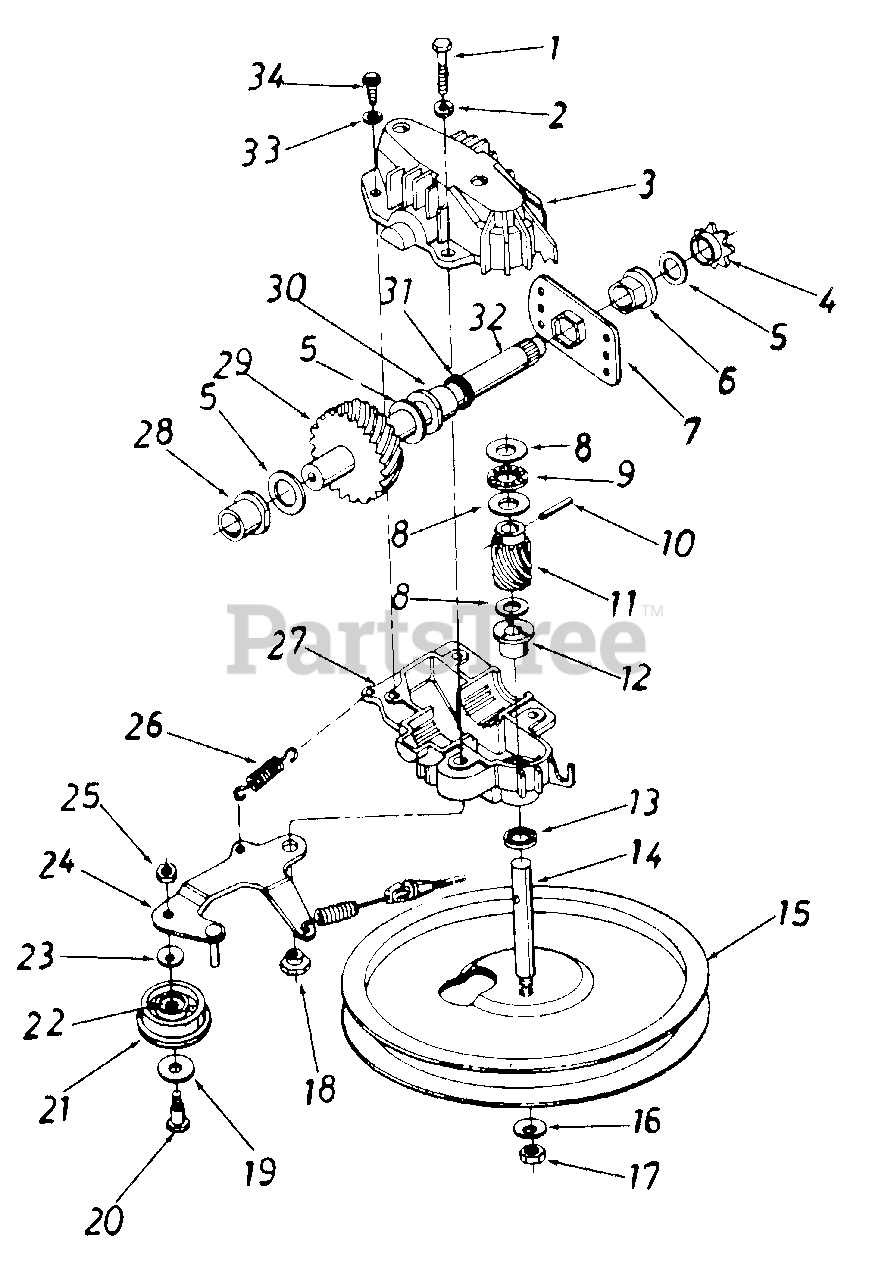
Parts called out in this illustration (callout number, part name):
1	Hex Bolt 1/4-20 x 1.25" Lg.
2	L-Wash. 1/4" I.D.*
3	Upper Transmission Hsg. Half
4	#48 Sprocket 7 Tooth x 1/2 0 Pitch
5	Fl-Wash. 5/8" I.D. x .030
6	Hex Flange Brg. .631" I.D.
7	Hex Bearing Cup
8	Thrust Wash. .382" I.D. x .70" O.D.
9	Thrust Bearing .375" I.D. x .812" O.D.
10	Spring Pin Spir. 1/8" x .62" Heavy
11	11 Tooth Helical Gear
12	Flange Bearing
14	Pulley-Transmission Shaft .375 O.D.
15	Fl-Pulley 5.06" O.D.
16	Bell-Wash. .265" I.D. x .75" O.D.
17	Hex Lock Nut 1/2-20 Thd.
18	Shld. Spacer .375" Dia. x .170
19	Fl-Wash. .390" I.D. x 1.0" O.D.
20	Shld. Bolt .375" Dia. x .400" Lg.
21	Fl-Idler Plastic 1.50" Dia. x .48
22	Needle Brg. .375" x .31
23	Bell-Wash. .265" I.D. x .75" O.D.
24	Idler Brk't. Ass'y.
25	Hex Patch L-Nut 1/4-20 Thd.
26	Extension Spring 1.12" Lg.
27	Lower Transmission Hsg. Half
28	Flange Bearing .566 Dia.
29	33 Tooth Helical Gear
30	Flange Bearing .629 Dia.
31	Oil Seal .625 Dia.
32	Gear Sprocket Shaft
34	Hex B-Tap Scr. #10 x .62" Lg.
